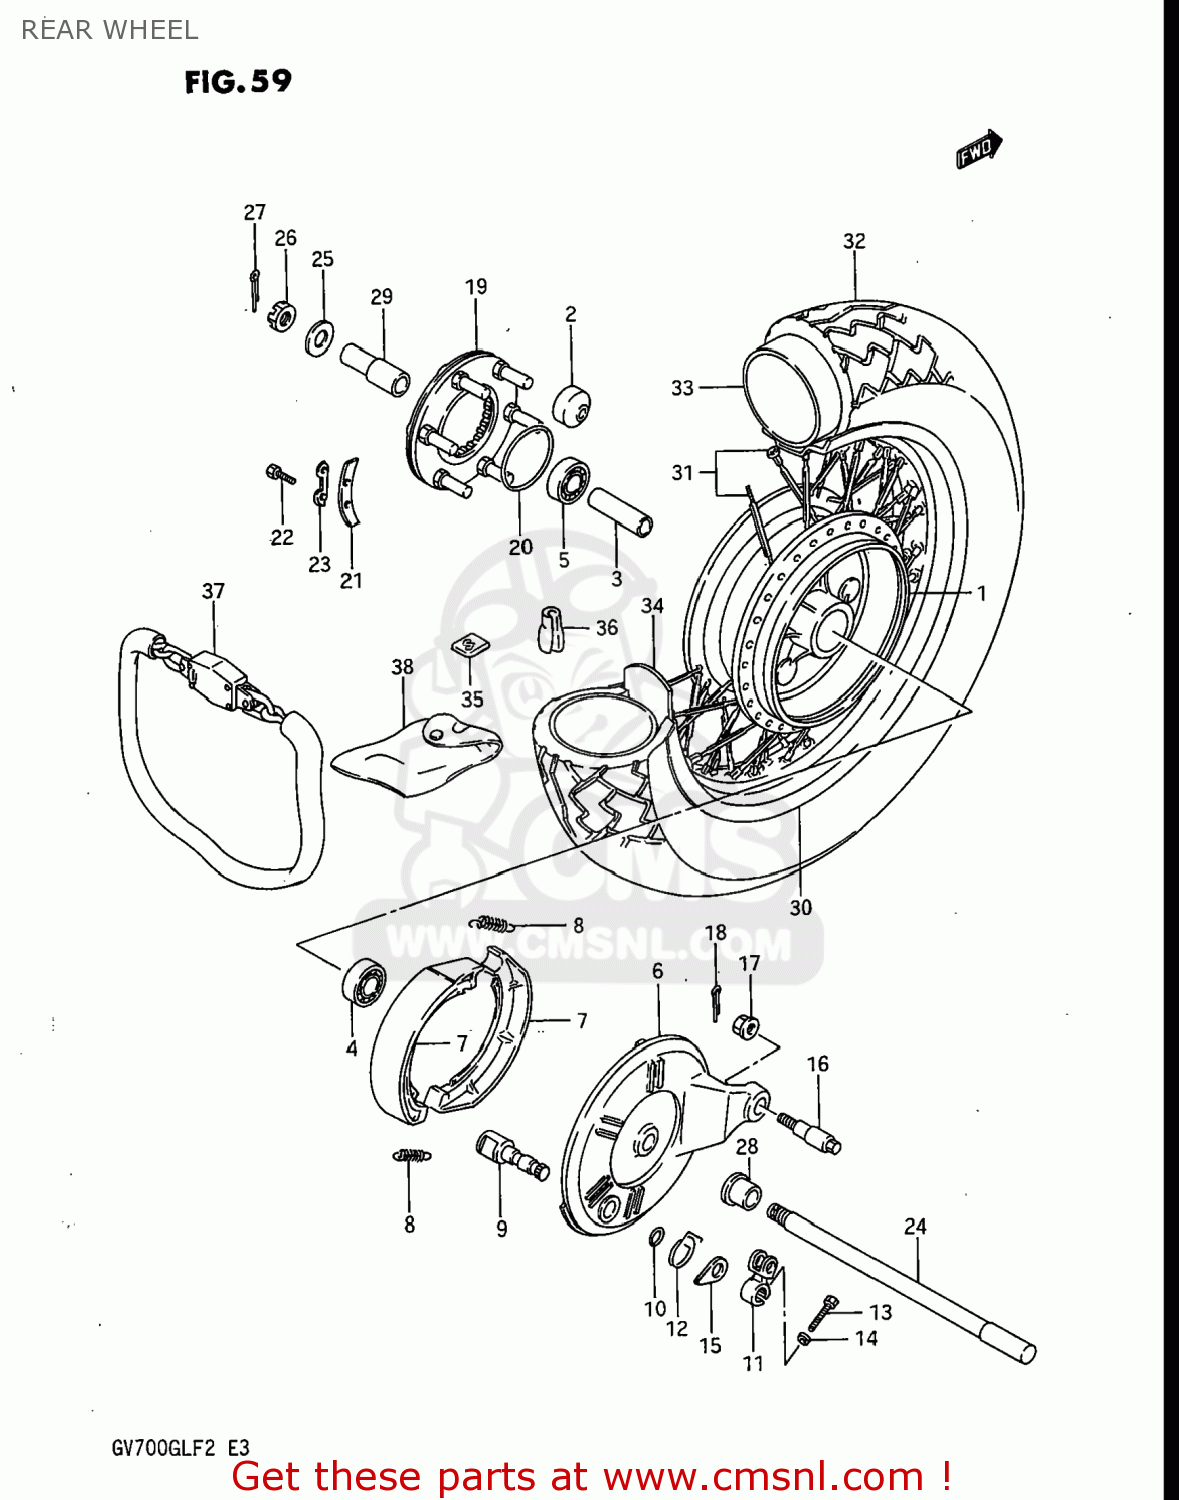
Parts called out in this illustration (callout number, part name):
1	DRUM SET,REAR HUB
2	BUSH
3	SPACER,REAR HUB BEARING
4	BEARING
5	BEARING
6	PANEL,REAR HUB
7	SHOE SET,BRAKE (MCA)
8	SPRING,BRAKE SHOE
9	CAM,REAR BRAKE
10	O-RING,BOSS
11	LEVER,REAR BRAKE CAM
12	SPRING
13	BOLT
14	LOCK WASHER
15	PLATE,BRAKE LINING INDICATOR
16	PIN,REAR PANEL TORQUE ST
17	NUT
18	COTTER PIN
19	JOINT ASSEMBLY,REAR HUB DRUM
20	O RING(D:2.1,ID:65)
21	WASHER,THRUST(T:1.6)
22	BOLT(6X16)
23	WASHER
24	AXLE,REAR
25	WASHER(16.5X36X3.2)
26	NUT
27	PIN,COTTER
28	SPACER,REAR AXLE
29	SPACER,REAR AXLE,LEFT
30	RIM,REAR WHEEL (3.00X16)(
31	SPOKE SET,REAR WHEEL
32	TIRE 140/80-16
33	TUBE ASSY,WHEEL INNER
34	PROTECTOR,WHEEL,INNER
35	BALANCER,WHEEL NO.1
36	BALANCER,WHEEL
37	CHAIN LOCK ASSY
38	BAG,CHAIN LOCK
